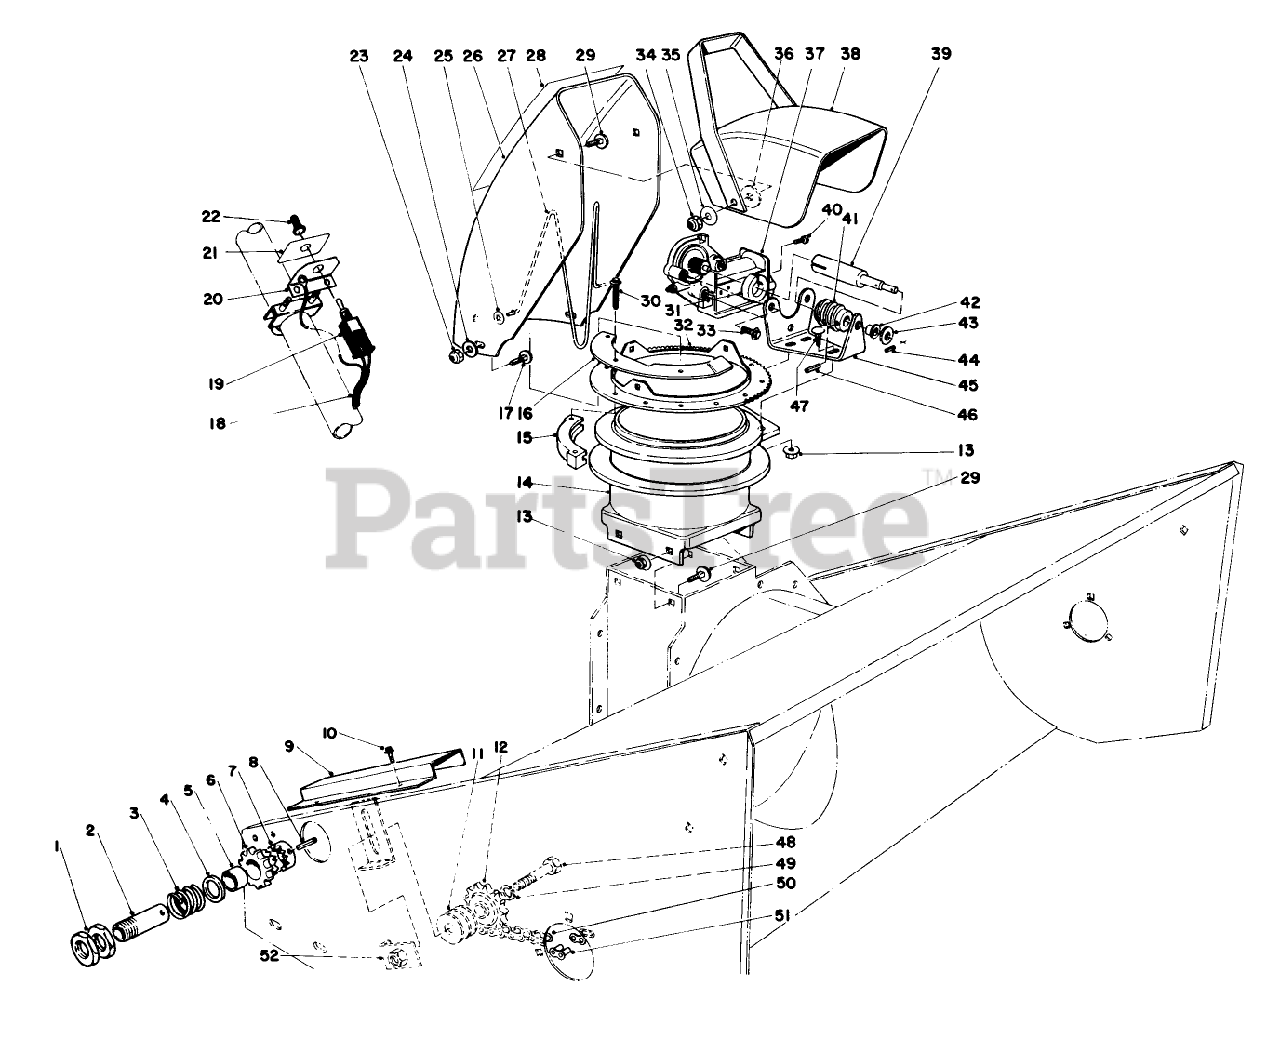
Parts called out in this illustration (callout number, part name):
1	THIN NUT
2	Clutch Sleeve
3	Spring Compression
6	Clutch Sprocket
7	Clutch Collar
8	PIN-ROLL
9	Chain Cover
10	SCREW-HWHTF
11	WASHER-FLAT
12	IDLER SPRKT (60016)
13	NUT-HHF, WHIZ
14	Chute Transition
15	RETAINER-CHUTE
16	Stop-Chute Rotator
17	SCREW-CARR
18	WIRE HARNESS
19	Toggle Switch
20	Toggle Switch Mount
21	DECAL
22	BOOT-SWITCH
23	NUT-LOCK, NI
24	WASHER-PLAIN
25	NUT-PUSH
26	Upper Chute
27	WIRE-CHUTE
28	Decal-Warning
29	SCREW-CARR
30	SCREW-SPECIAL
31	SPLIT COLLAR
32	RING - CHUTE SWIVEL
33	SCREW-HHF
34	NUT-LOCK, CONE
35	WASHER-BELLEVILLE
36	WASHER-RUBBER
37	ELEC GEAR MOTOR
38	Deflector
39	WORM GEAR SHAFT
40	SCREW-HSH
41	GEAR-WORM, CHUTE
42	FLANGE BSHG #FF-310-3
43	WASHER-FLAT
44	3/32 X 9/16 ROLL PIN
45	Motor Mount
46	PIN-SPRING
47	BOLT-CARR
48	SCREW-HH
49	WASHER-LOCK
50	ROLLER CHAIN (60023)
51	LINK-CHAIN
52	NUT PLATE WA (60095)
